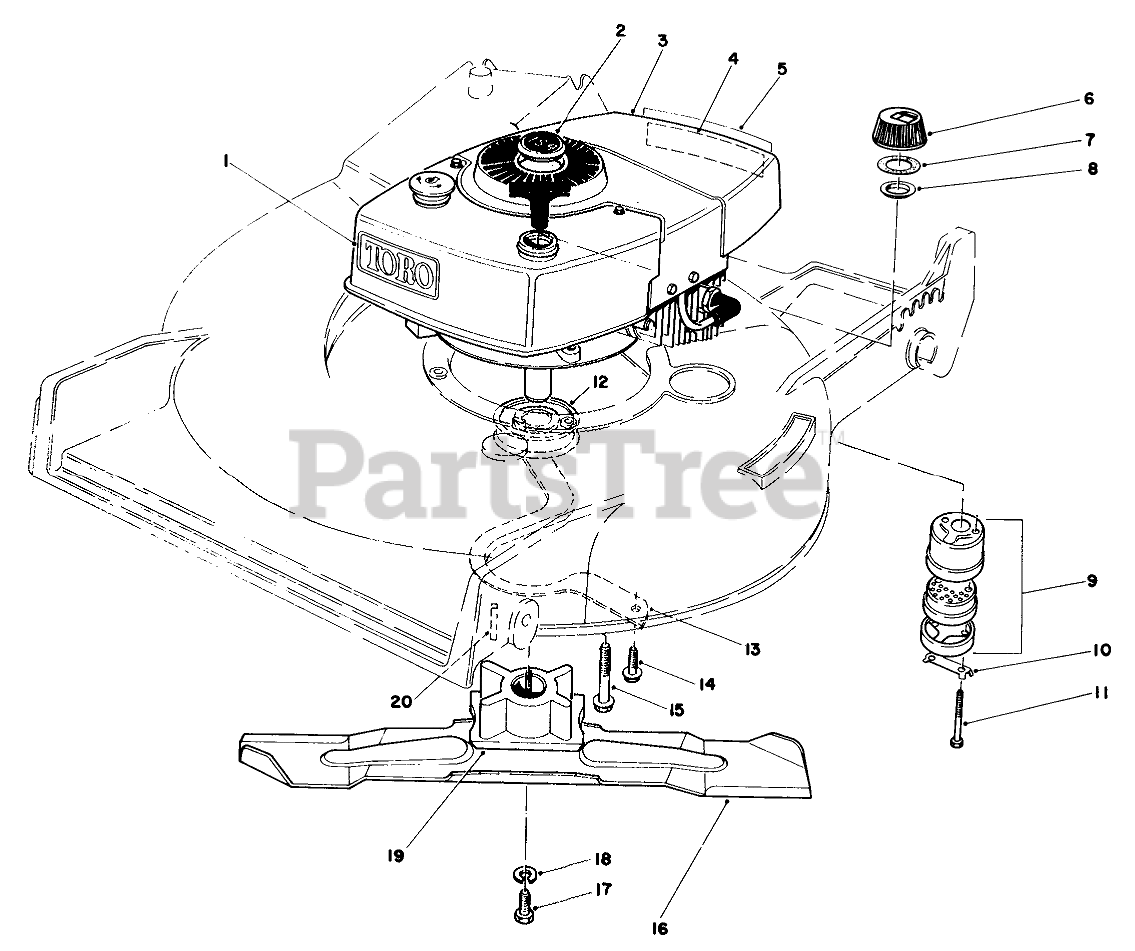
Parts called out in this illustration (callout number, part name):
1	Decal Tow
2	Plug Button
3	Engine
4	Decal Maintenance
5	Decal-Primer
6	Gas Cap (Incl. Ref. #7 & 8)
7	GASKET
8	GAS CAP BAFFLE
9	Muffler Assembly (Incl. Ref. #10 & 11)
10	CLIP - LOCKING
11	SCREW-HH
12	Pulley
13	BELT GUIDE
14	Screw
15	3/8-16 X 2 CAPSCREW
16	BLADE-21in
17	SCREW-BLADE
18	WASHER-LOCK
19	BLADE RETAINER(DEEP)
20	KEY-SQUARE
